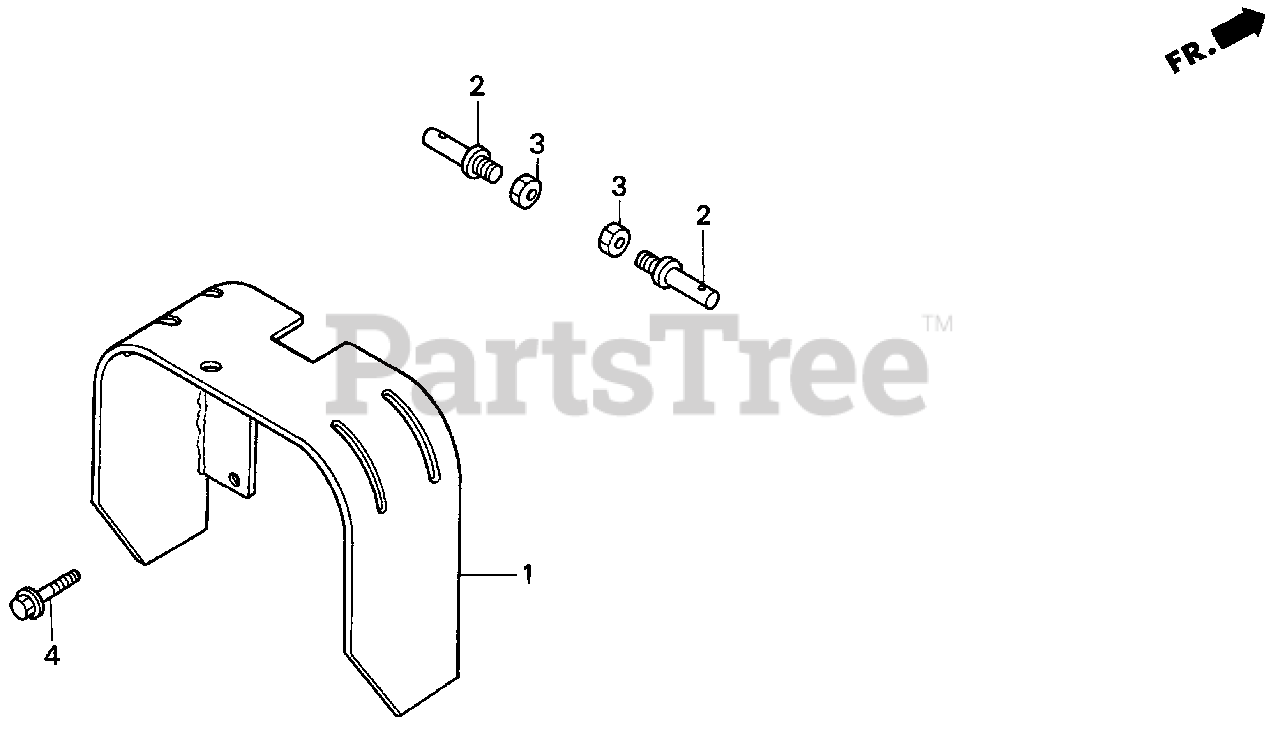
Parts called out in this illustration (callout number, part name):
1	SHIELD, RR. P.T.O. MASTER
1	SHIELD, RR. P.T.O.
2	PIN, LIFT ARM
3	NUT, SPECIAL (16MM)
4	BOLT, FLANGE (12X30)
